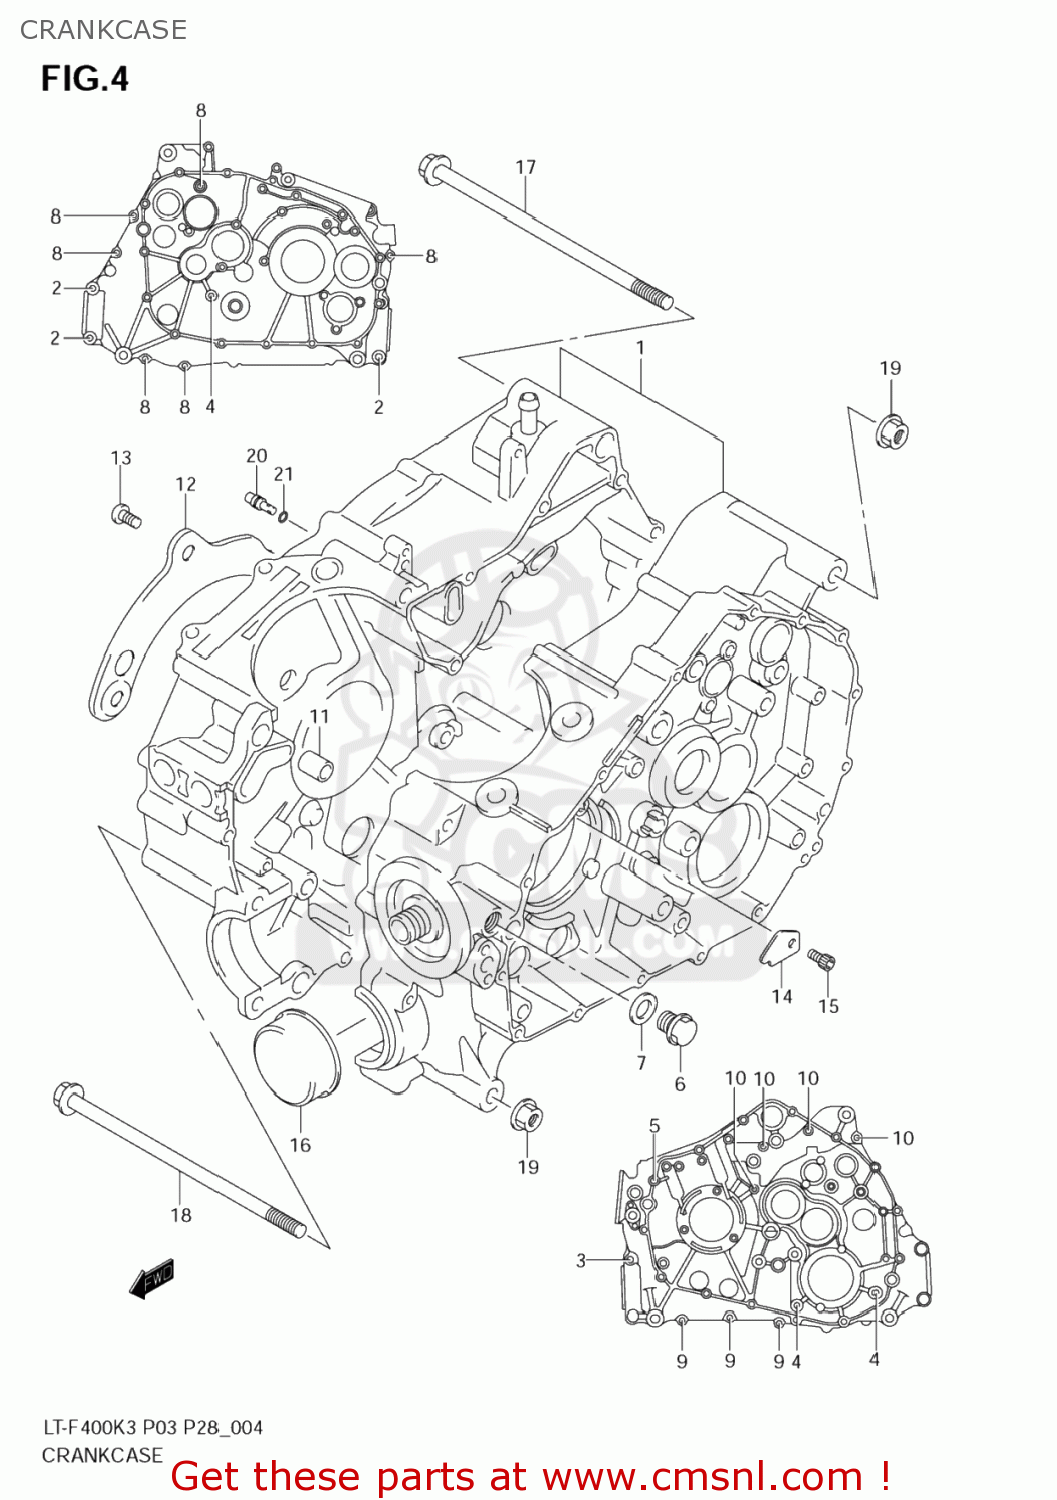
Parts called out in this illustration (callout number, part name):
1	CRANKCASE SET
2	BOLT(8X50)
3	BOLT(8X50)
4	BOLT(8X85)
5	BOLT 8X60
6	PLUG(14X12)
7	GASKET(13.8X18.8X4.8) (NAS)
8	BOLT
9	BOLT
10	BOLT
11	PIN
12	PLATE,OIL GUIDE
13	SCREW
14	PLATE,OIL GUIDE,L
15	SCREW
16	PLUG,CRANKCASE
17	BOLT(10X195)
18	BOLT(10X180)
19	NUT
20	JET,OIL GALLERY(16)
21	O RING(D:1.2,ID:4)
